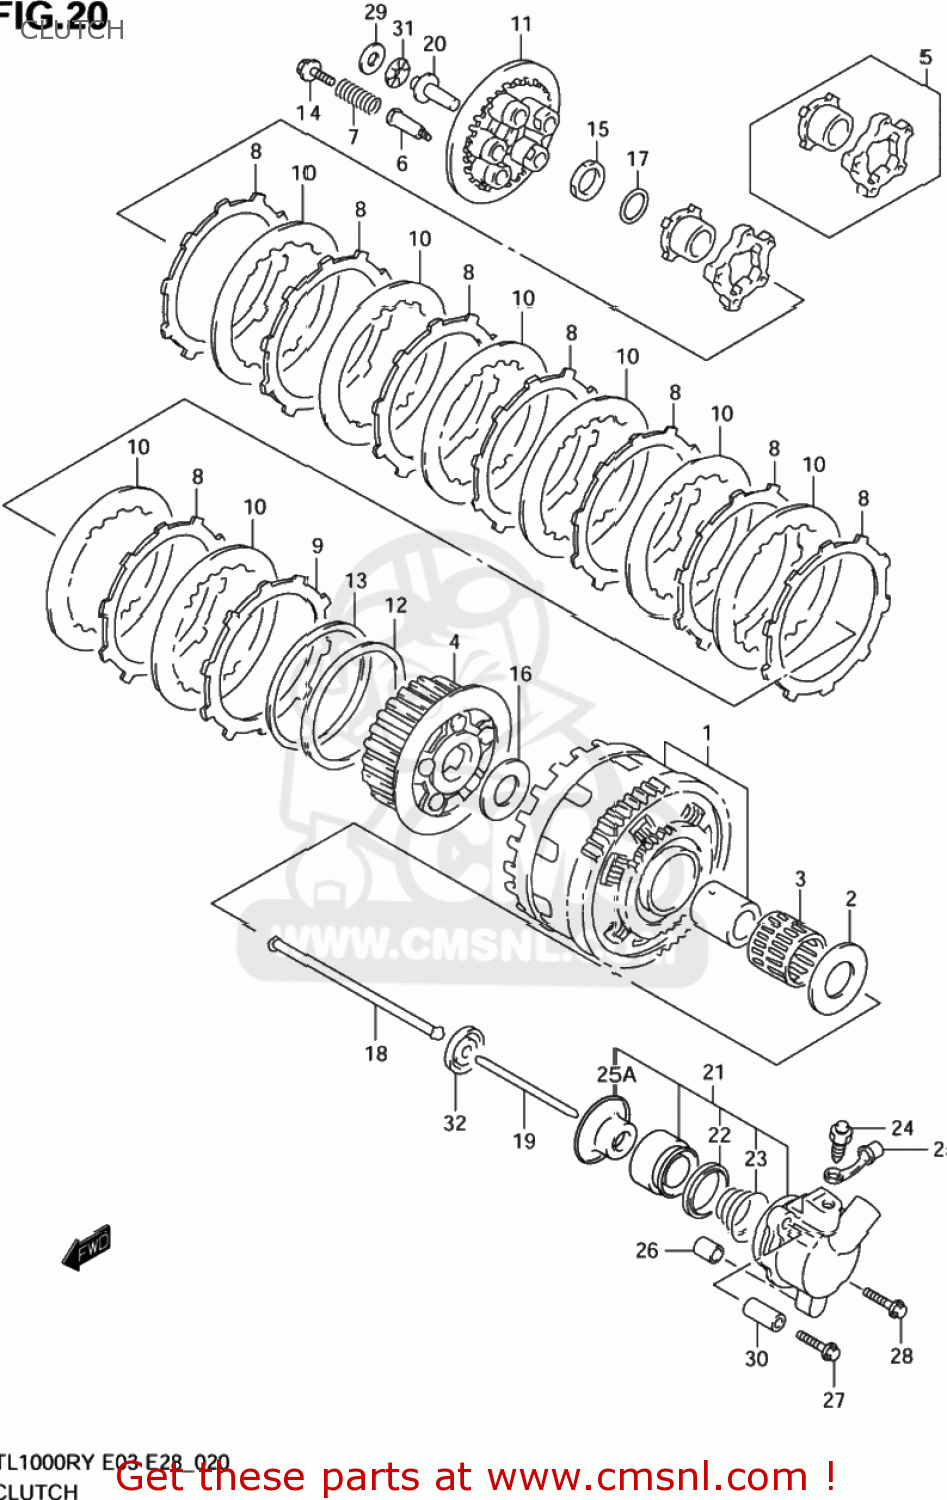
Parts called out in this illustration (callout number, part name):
1	GEAR ASSY,PRI DRIVEN
2	WASHER(25X54X2.5)
3	BEARING(35X40X35.8)
4	HUB,CLUTCH SLEEVE
5	CAM SET,CLUTCH
6	BOLT,SPRING SUPPORT
7	SPRING,CLUTCH
8	PLATE,CLUTCH DRIVE (NAS)
9	PLATE,CLUTCH DRIVE NO (NAS)
10	PLATE,CLUTCH DRIVEN (NAS)
11	DISC,CLUTCH PRESSURE
12	SEAT,WAVE WASHER
13	WASHER,CLUTCH PLATE WAVE
14	BOLT,CLUTCH SPRING
15	NUT
16	WASHER(25X50X2.5)
17	WASHER
18	ROD,CLUTCH PUSH,R
19	ROD,CLUTCH PUSH,L
20	PIECE,CLUTCH PUSH
21	CYLINDER,CLUTCH RELEASE
22	CUP
23	SPRING
24	BLEEDER
25	CAP,BLEEDER
25A	COVER,DUST
26	PIN
27	BOLT
28	BOLT
29	WASHER(15.5X28X1)
30	SPACER(6.2X12X50)
31	BEARING(15X28X2)
32	SEAL,OIL(6X34X5.5)
